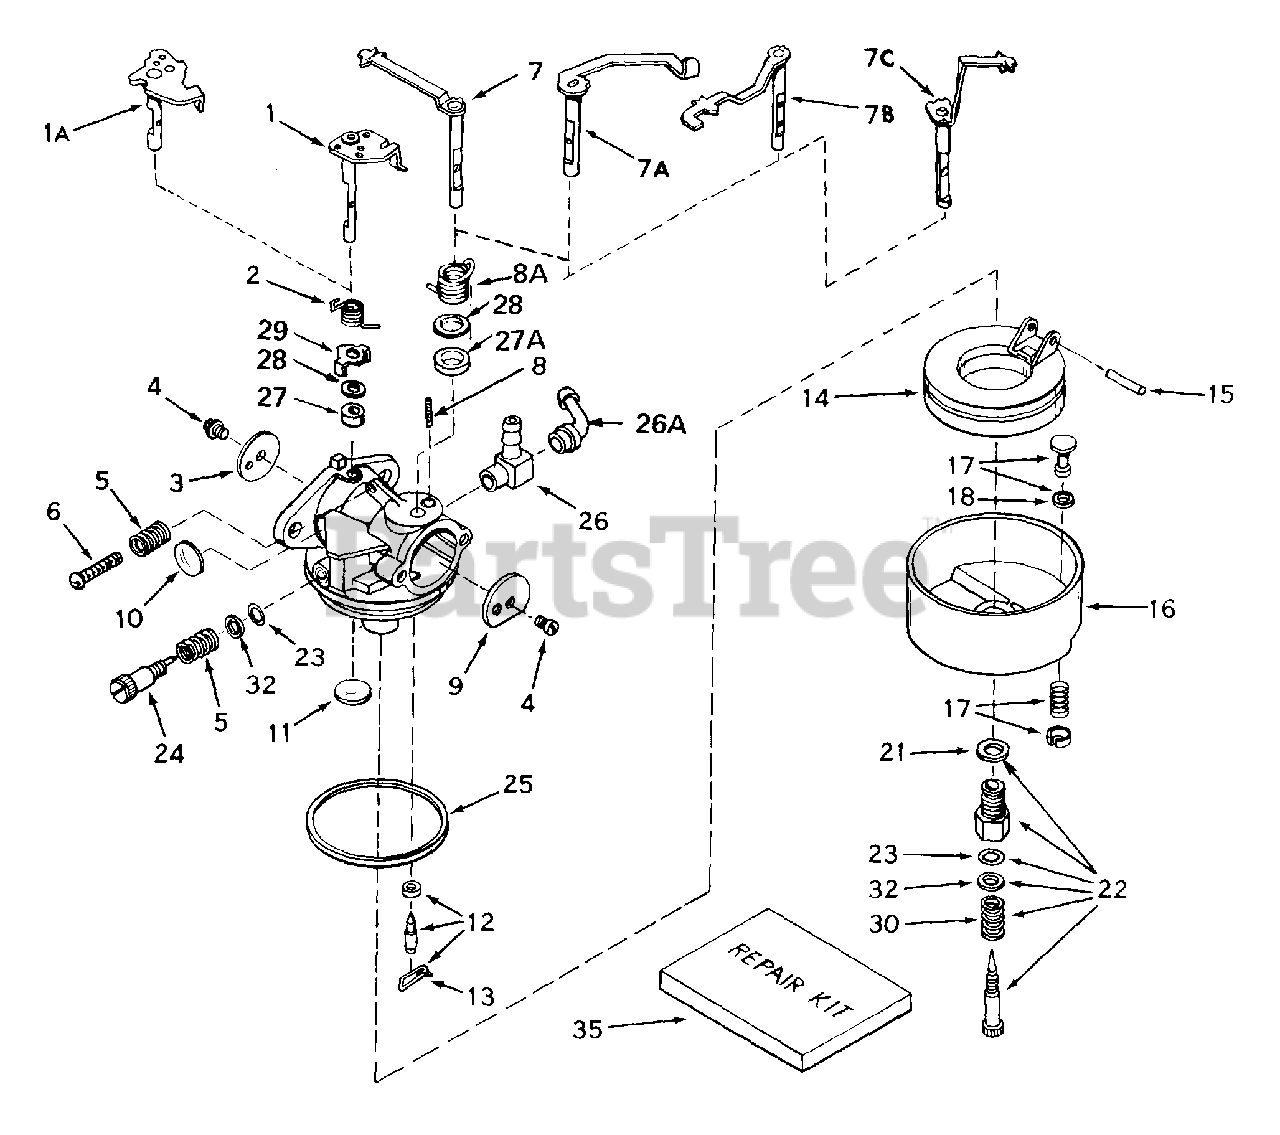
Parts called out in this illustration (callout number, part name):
1	"Shaft & Lever Assy., Throttle
2	Spring, Throttle return
3	Shutter, Throttle
4	Screw, Throttle & Choke shutter
5	Spring, Regulating screw
6	Screw, Idle regulating
7C	Shaft & Lever Assy., Choke
8	Spring, Choke positioning
8A	Spring, Compression
9	Shutter, Choke
10	Plug, Welch
11	Plug, Welch
12	Inlet Needle, Seat & Clip Assy.
13	Clip, Inlet needle
14	Float, Carburetor
15	Shaft, Float
16	Bowl, Float
21	Gasket, Bowl-to-body
22	Adj. Screw Assy., Main
23	"O" Ring, Adj. screw
24	Screw, Idle adj.
25	Gasket, Bowl-to-body
26	Fitting, Fuel inlet
27	Seal, Dust
27A	Seal, Dust
29	Retainer, Dust seal
30	Spring, Main adj. screw
35	Repair Kit
